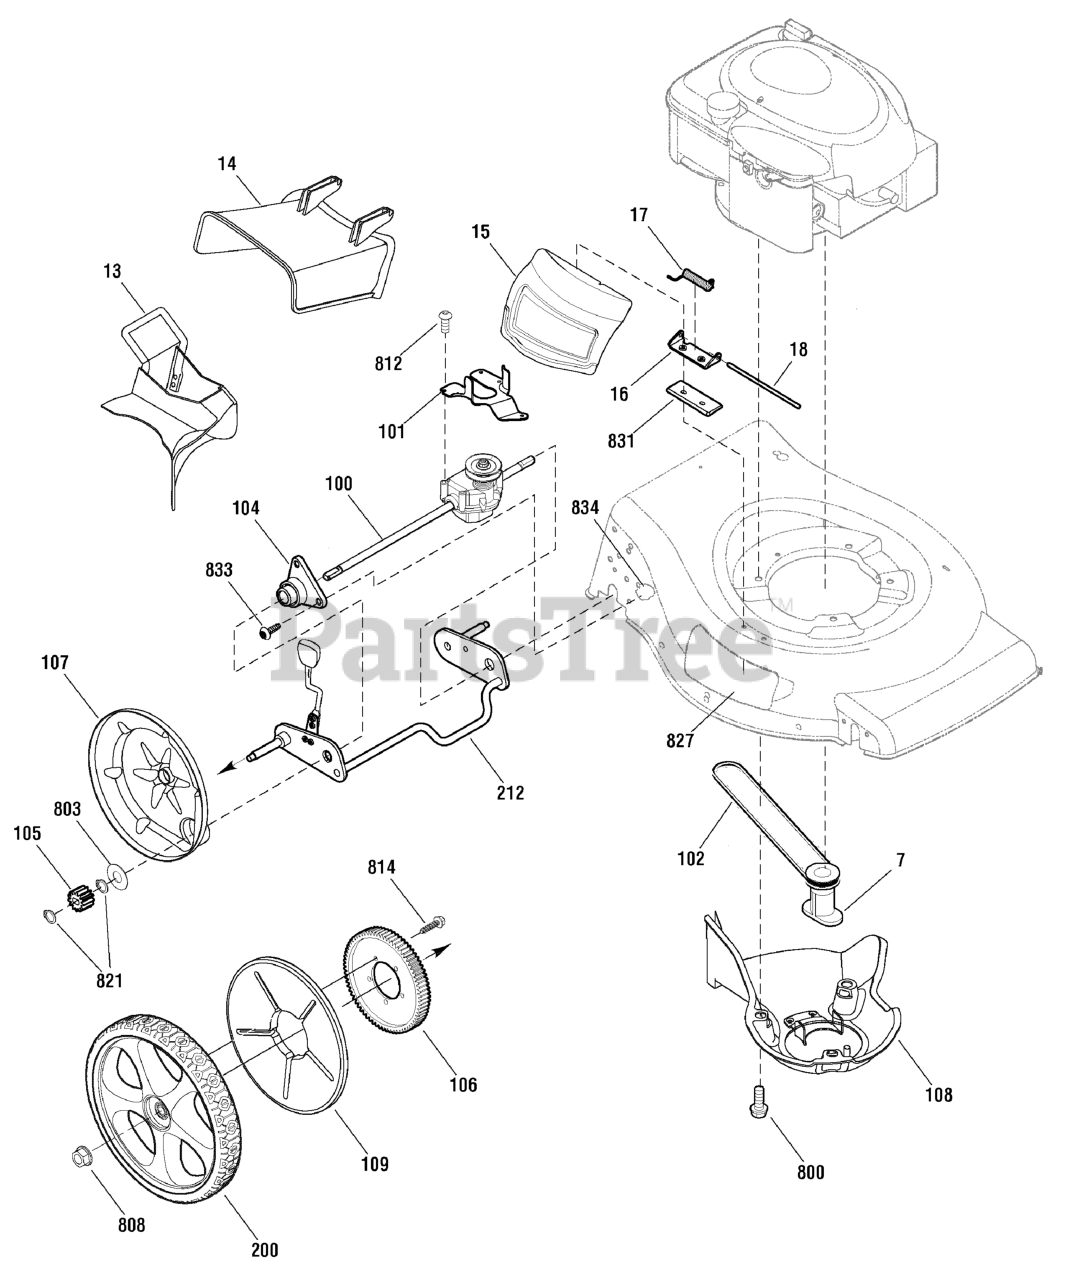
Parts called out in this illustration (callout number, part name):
7	BLADE ADAPTER ASSEMBLY
13	MULCH PLUG
14	CHUTE DEFLECTOR
15	MULCH COVER
16	BRACKET, Chute Deflector
17	SPRING, Chute Deflector
18	ROD, Chute Deflector
100	TRANSMISSION
101	BELT GUIDE, Transmission
104	SLEEVE ASSEMBLY, Rear Axle
105	GEAR, Pinion
106	GEAR, Drive
107	DUST COVER
108	BELT COVER ASSEMBLY
109	COVER, Wheel
200	WHEEL, Rear
212	CROSSBAR ASSEMBLY, Rear
800	SCREW, Hex Head, 3/8-16 x 1
803	WASHER, Thrust
808	NUT, Flange, 3/8-16
812	SCREW, #10 x 1
814	SCREW, 1/4-15 x 3/4
821	RING, External Retaining
827	SCREW, 1/4-20 x 7/8
833	SCREW, Torx, 1/4-20 x 5/8
834	NUT, Flange Lock, 1/4-20
